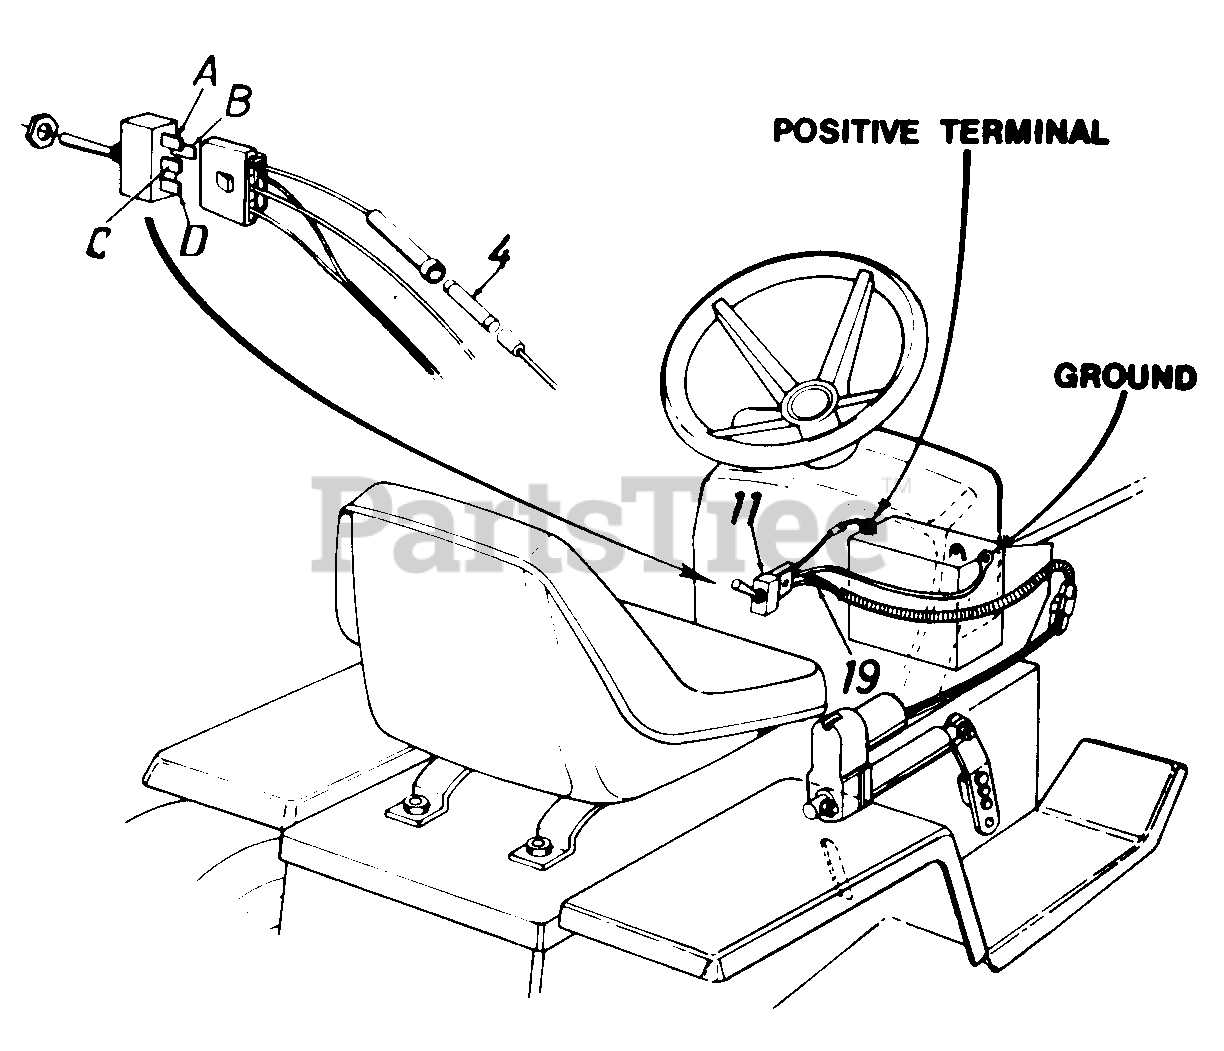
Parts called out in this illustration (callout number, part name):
4	Fuse 30 AMP
11	Toggle Switch
19	Wire Harness
A	Blue Wire Connects to Positive Terminal on Battery
B	Yellow Wire Connects to Actuator
C	Black Wire Ground Wire -to Frame
D	Red Wire Connects to Actuator
